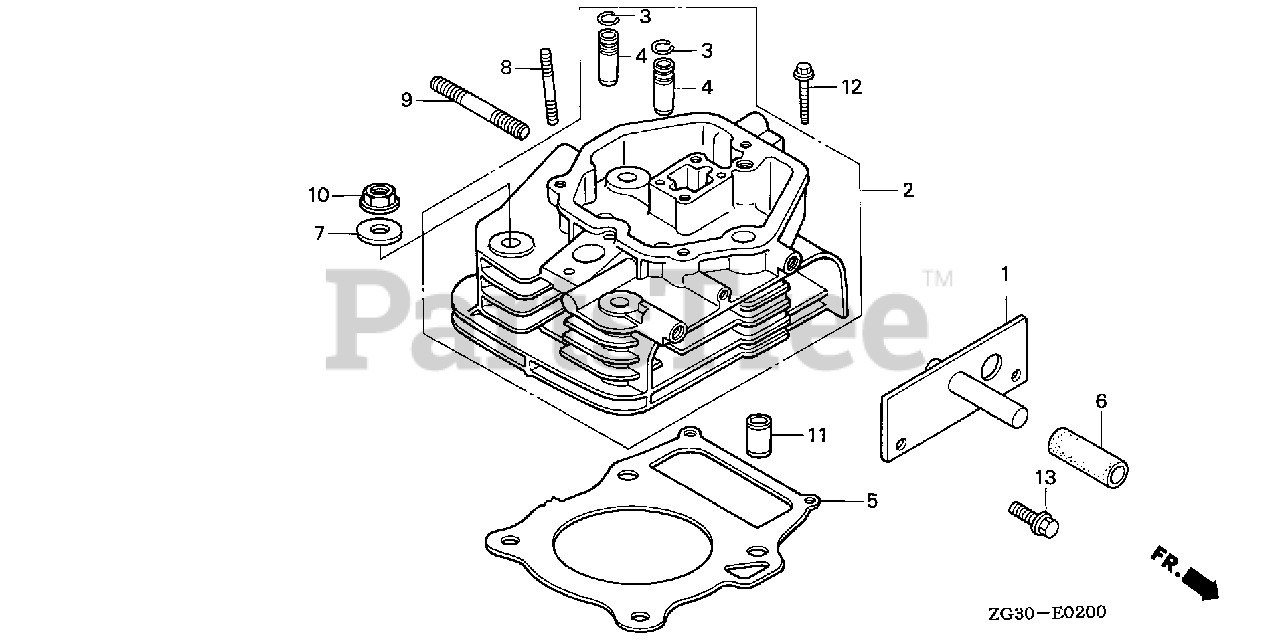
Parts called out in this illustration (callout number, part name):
2	CYLINDER HEAD
3	CLIP, VALVE GUIDE
4	GUIDE, VALVE (OVER SIZE)
5	GASKET, CYLINDER HEAD (1.1) (A)
5	GASKET, CYLINDER HEAD (1.2) (B)
5	GASKET, CYLINDER HEAD (1.3) (C)
5	GASKET, CYLINDER HEAD (1.4) (D) (NOT AVAILABLE)
7	WASHER (10MM)
8	BOLT, STUD (6X32)
9	BOLT, STUD (8X28)
10	NUT, FLANGE (10MM)
11	PIN, DOWEL (12X20)
12	BOLT, FLANGE (6X28)
